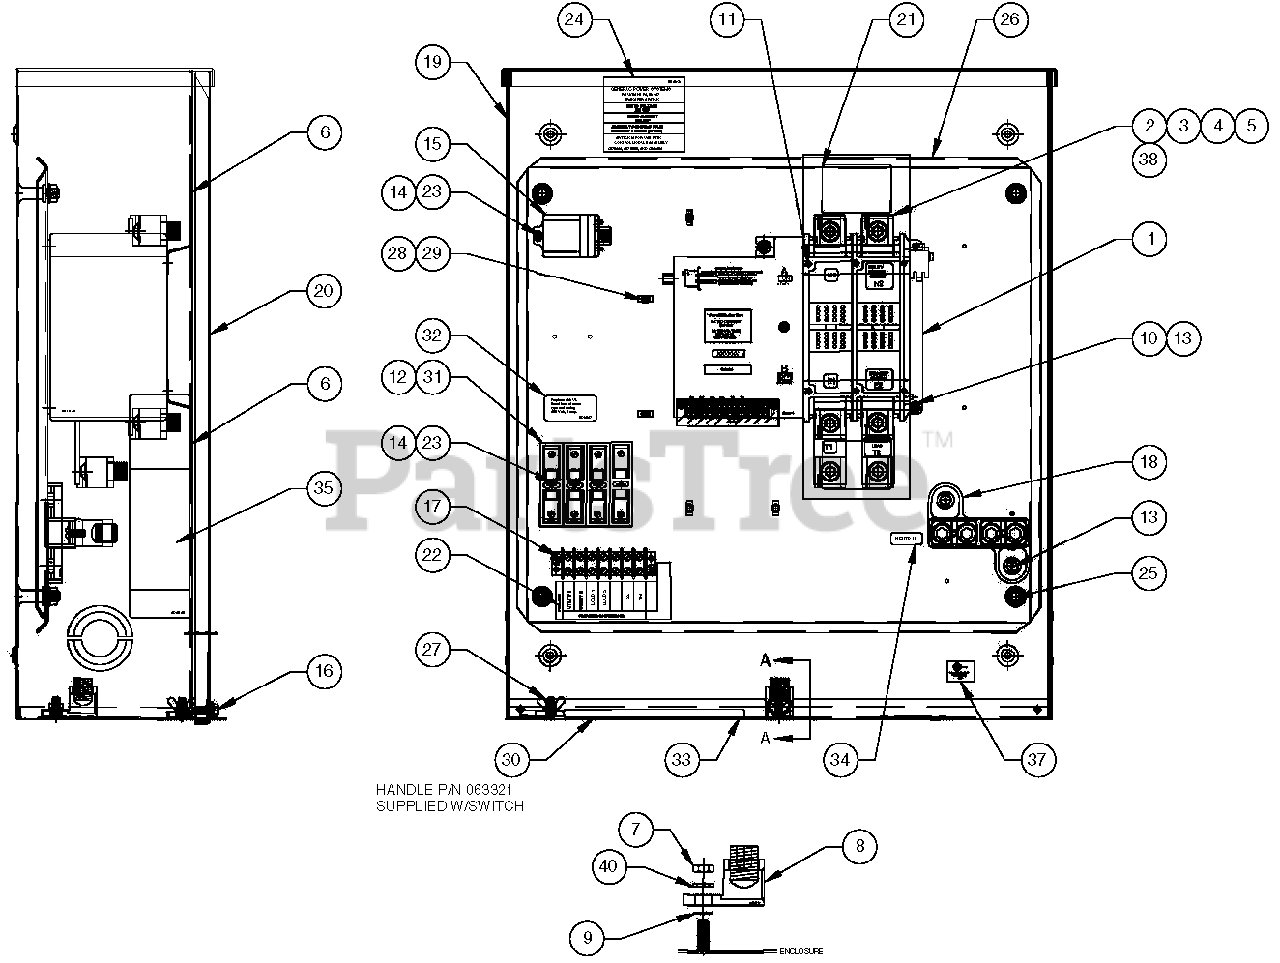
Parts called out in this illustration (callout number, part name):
1	XFER SW-W 200A600V2P
2	LUG SLDLSS 400-#4X1/4-20 CU7AL
3	SCREW FHM M8-1.25 X 20MM CR
4	NUT LOCK FL M8-1.25 YEL CHR
5	SCREW HHTT #8-32 X 1/4 CZ
6	COVER LUG 2P 150/200AMP
7	NUT HEX 1/4-20 STEEL
8	LUG SLDLSS 350-#6X13/32 AL/CU
9	WASHER SHAKEPROOF EXT 5/16 STL
10	WASHER LOCK M6-1/4
11	SCREW PPHM DSEMS M4-7 X 10 ZNC
12	FUSE HOLDER
13	SCREW HHTT M6-1.0 X 12 ZINC
14	SCREW HHTT M4-0.7 X 10 BP
15	RELAY PNL 12VDC DPDT 10A@240VA
16	SCREW TH-FRM M6-1X16 N WA Z/JS
17	RIVET POP .156 X .675 AL
18	ASS'Y-NTRL BL150-200A
19	WELDMENT,TRANSFER SWITCH BOX
20	COVER, TRANSFER SWITCH BOX
21	DECAL TERMINAL SHOCK HAZARD
22	DECAL TERMINAL STRIP
23	WASHER LOCK #8-M4
24	DECAL,SWITCH RATING
25	NUT LOCK FL 3/8-16
26	SUBPLT 200A TS 3R
27	NUT WING 1/4-20
28	HOLDER CABLE TIE
29	TIE WRAP UL 5.6 X .10 NATL
30	HANDLE XFER SWITCH 1-400A
31	FUSE 5A X BUSS
32	DECAL, FUSE REPLACEMENT
33	DECAL GROUND LUG
34	DECAL NEUTRAL
35	DECAL, MANUAL OPERATION
36	DECAL,TEST SEQUENCE 2P TS 3R
37	DECAL-UL LIST HSB
38	DECAL,LUG TORQUE INFO
39	DECAL,TRANSFER SWITCH
40	WASHER LOCK M8-5/16
